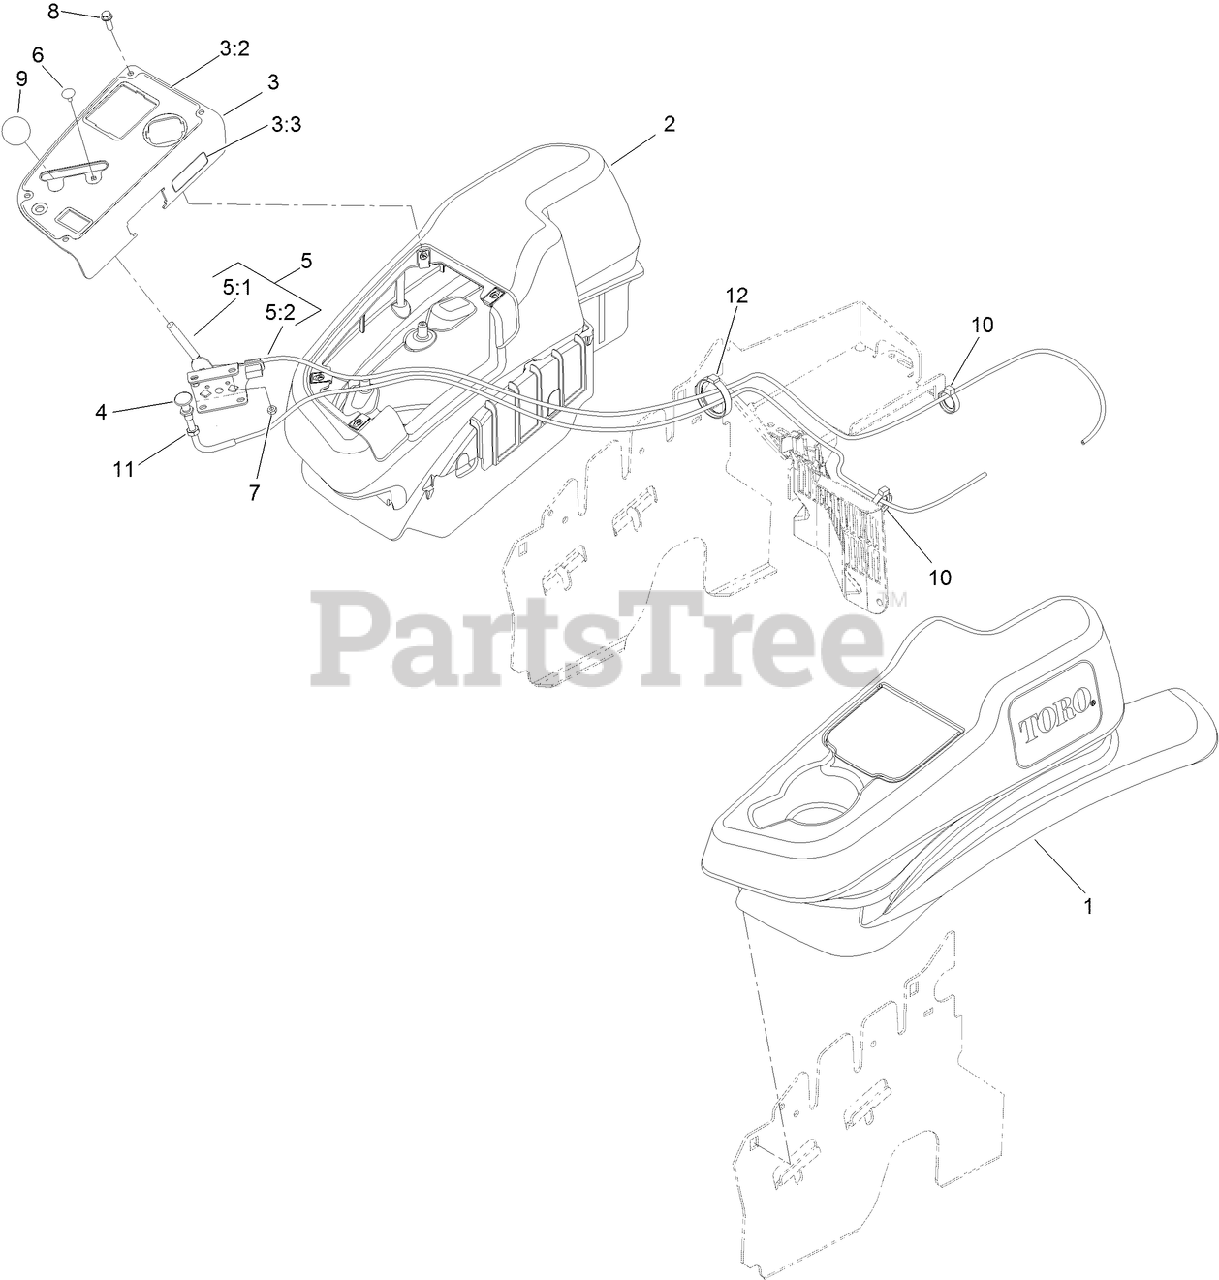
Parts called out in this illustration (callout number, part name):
1	LH NARROW FENDER/CONSOLE ASM
2	RH NARROW FENDER/CONSOLE ASM
3	CONTROL PANEL ASM
3:2	DECAL-CONTROL PANEL
3:3	DECAL-FUSES
4	CONTROL-CHOKE
5	THROTTLE CONTROL ASM
5:1	LEVER-THROTTLE
5:2	CABLE-THROTTLE
6	BOLT-CARR
7	NUT-LOCK, NI
8	SCREW-HWH
9	KNOB-BALL
10	CLAMP-HOSE
11	NUT-HJ
12	CLAMP-HARNESS
